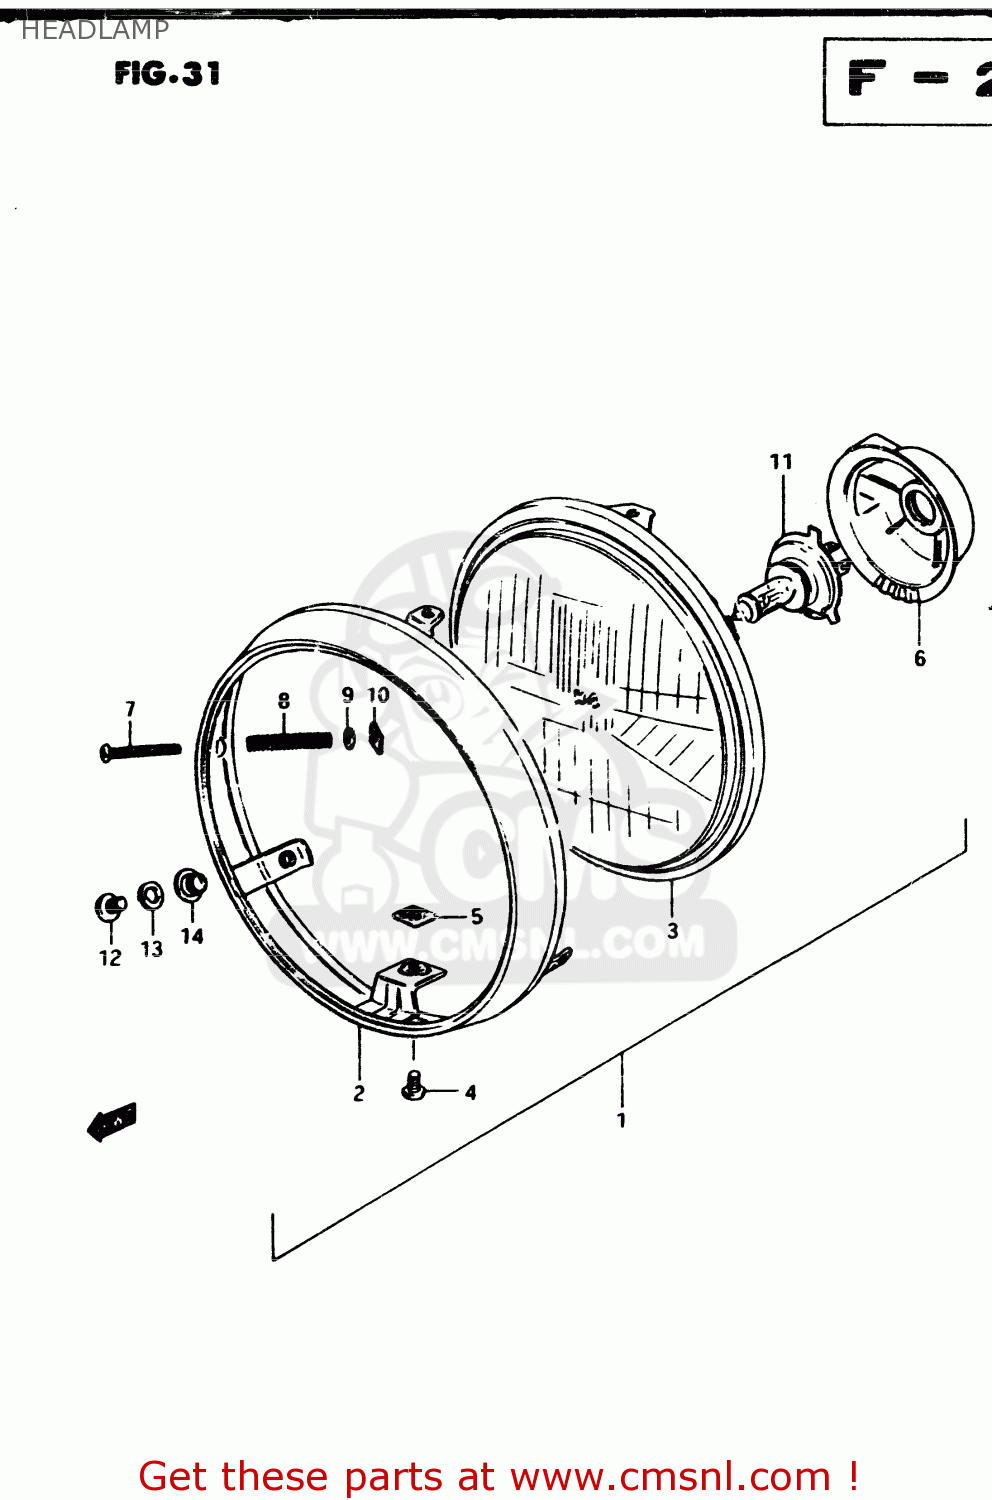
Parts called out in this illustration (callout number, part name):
1	HEADLAMP ASSEMBLY
2	RIM
3	LAMP UNIT
4	SCREW
5	NUT,ADJUSTING
6	COVER,SOCKET
7	SCREW,HEADLAMP ADJUST
8	SPRING
9	WASHER
10	NUT,HEADLAMP ADJUSTER
11	BULB(12V60/55W,H4)
12	SCREW
13	WASHER,LOCK
14	WASHER
